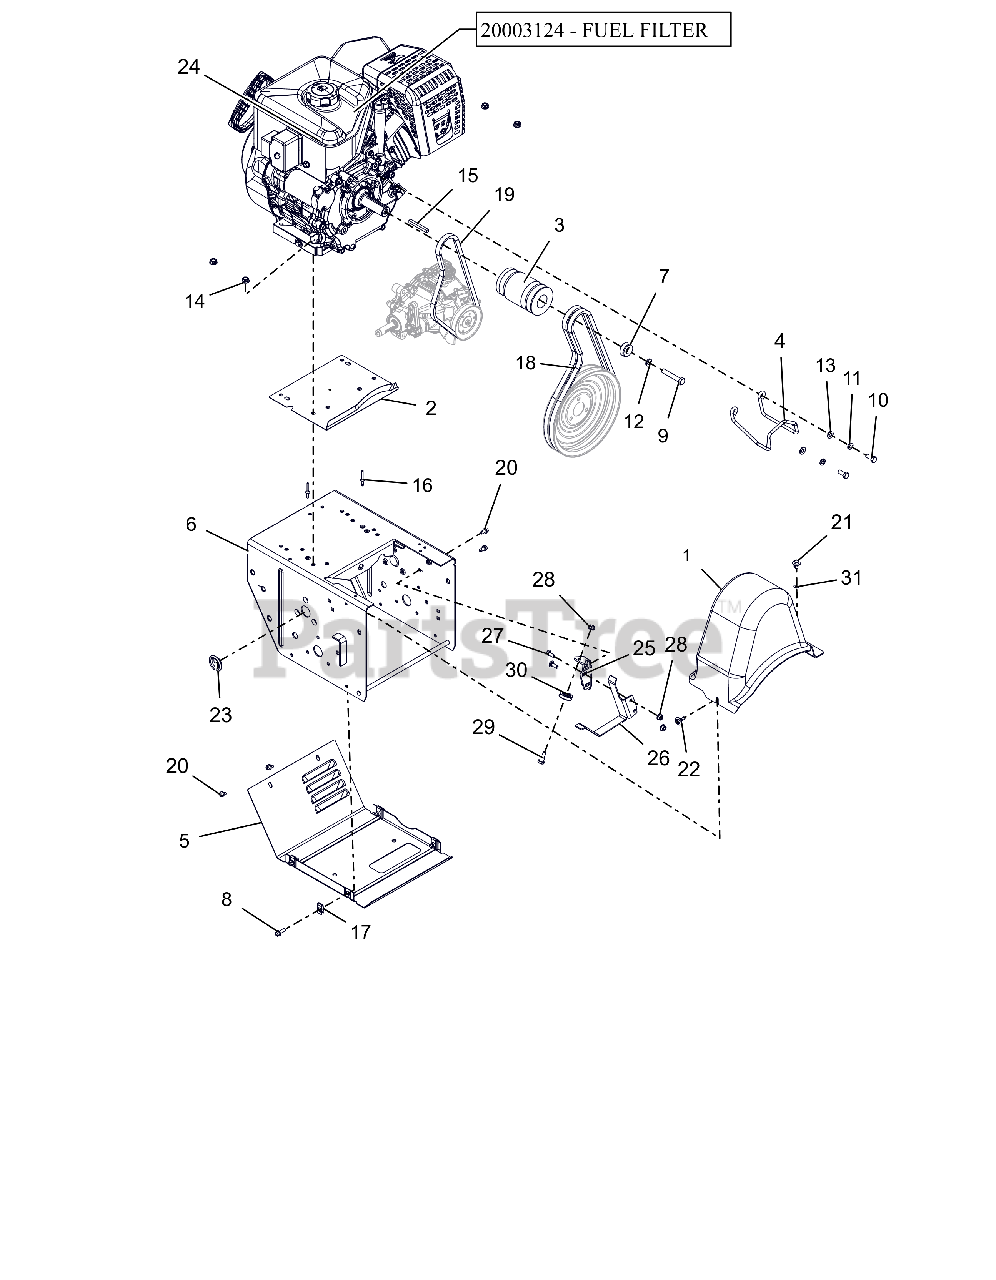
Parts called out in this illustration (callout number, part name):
1	COVER, BELT-LARGE
2	BAFFLE, WATER - LARGE BLOCK
3	SHEAVE, COMBO HYDRO WHEEL 4L
4	FINGER, BELT
5	COVER, BOTTOM - VENTILATED
6	FRAME, MAIN - PRO (WELDMENT)
7	BSHG-SPACER .47X1.25X.50
8	BLT-HEX .25-20X.75 HWH YZ GR5
9	BLT-HEX .38-24X2.25 YWZC GR5
10	BLT-HEX .31-24X.75 YWZC GR5
11	WSHR-LK .312X.097 HVY YWZC
12	@WSHR-LK .38X.094 REG YWZC
13	@WSHR-FL-STL.344X.688X.065YWZC
14	@NUT-LK-CTR-FLG .31-18 YZ GR F
15	KEY .25X.25X2.25
16	RVT-POP .187 YZ
17	NUT-RTNR .25-20X.56
18	V-BELT, HA-RAW EDGE (SET)
19	V-BELT, 4L-WRAPPED
20	SCR-TAP .25-20X.50 HWH TR YWZ
21	SCR-TAP .25-20X.50 LGHWH TR YZ
22	SCR-TAP .25-20X.5 CAPTIVE
23	PLUG, HOLE - 1.125"
24	ENGINE,EFI420 GEN3 120V/60W
24	FILTER, FUEL - IN-LINE EFI
25	BRACKET, CLUTCH CABLE
26	FINGER, BELT - FLAT
27	@BLT-RDHDSQNK .25-20X.75 G5YZ
28	@NUT-LK-TOP-FLG .25-20 YWZC
29	BOLT, SHLDR-.375X.375X.25-20
30	PULLEY, CABLE
31	NUT-PUSH .25X.50 O.D.
